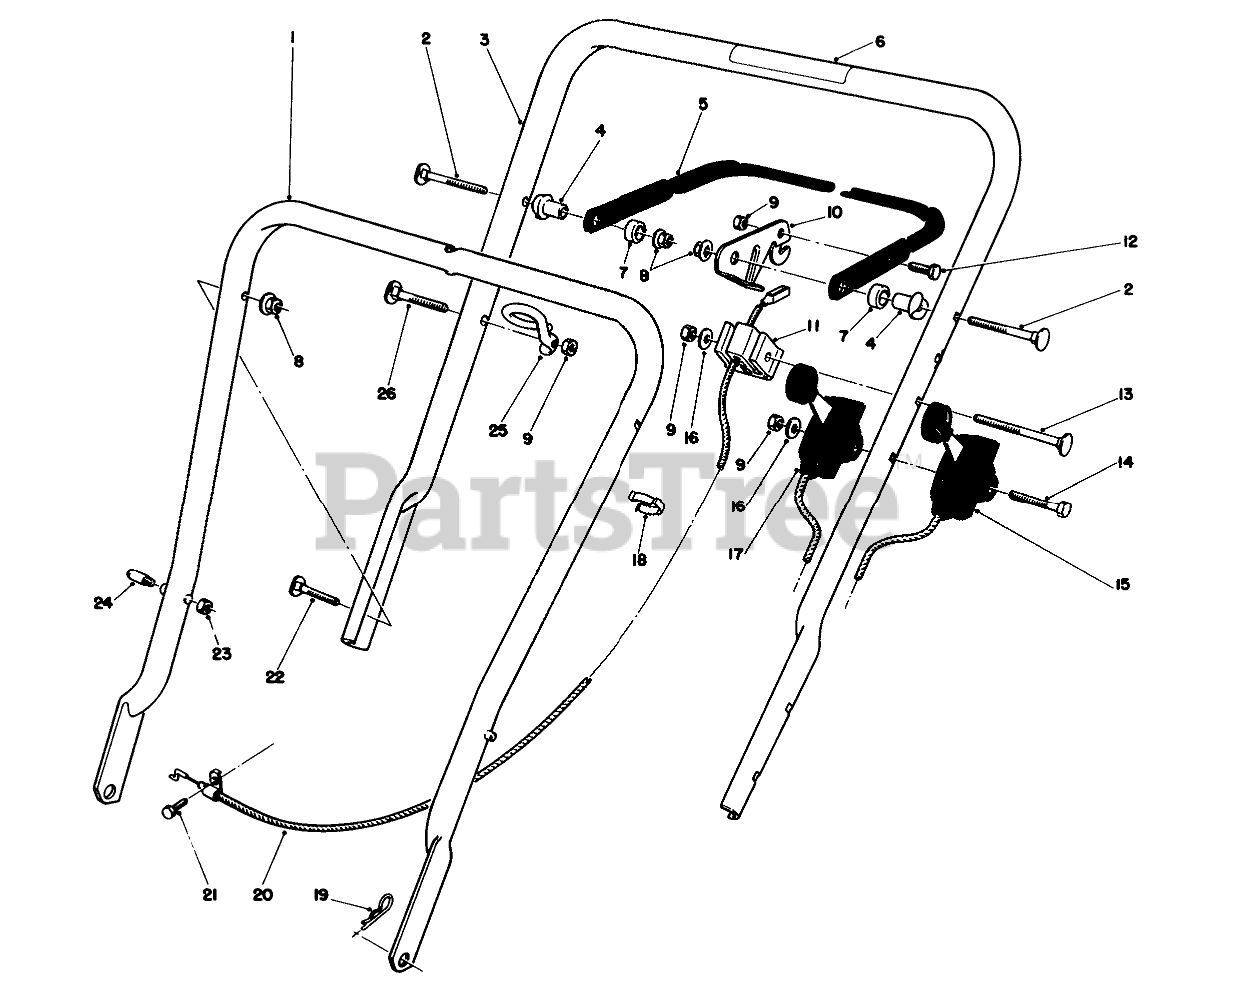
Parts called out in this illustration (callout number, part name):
1	LOWER HANDLE ASM
2	5/16-18 X 2 HNDLE SCREW
3	Handle-Upper (Incl. Ref. #6)
4	SPACER-SUPPORT
5	Bar-Control
6	Decal-Danger
7	SPACER-NYLON
8	NUT-LOCK, NI
9	NUT-LOCK, NI
10	LEVER-CONTROL
11	SUPPORT-CABLE
12	SCREW-HH
13	HANDLE SCREW
14	SCREW-HH
15	TRACTION CONTROL
16	WASHER-FLAT
17	THROTTLE CONTROL
18	BOWDEN CLIP
19	Hairpin Cotter
20	BRAKE CABLE
21	Capscrew
22	SCREW
23	NUT-LOCK, NI
24	HANDLE PIN
25	Guide
26	HANDLE SCREW
